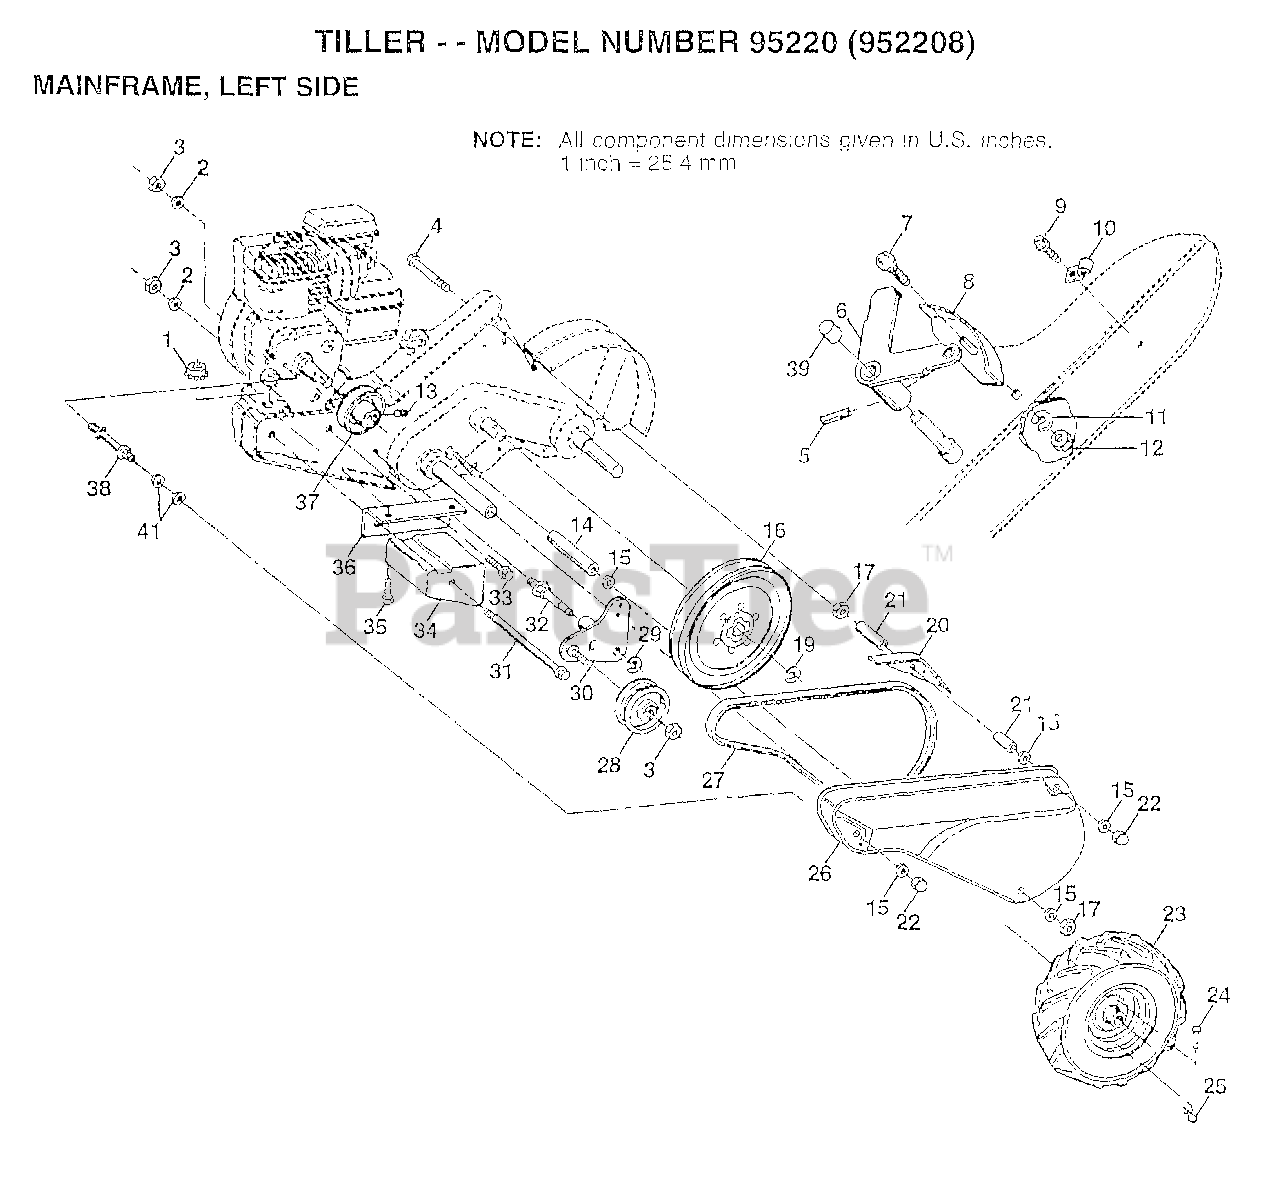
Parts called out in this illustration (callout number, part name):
2	LOCKWASHER
3	NUT.HEX.3/8-16UNC
4	BOLT TI
6	LEVER ASM CRT
7	BOLT
8	PANEL TI
10	CONDIUT CLIP T
11	LOCKWASHER
13	SET SCREW
14	SPACER
15	WASHER
16	SHEAVE.TRANS.
17	NUT.HEX.5/16-18
20	GUARD CRT
21	SPACER.SPLIT
22	NUT TI
23	TIRE.CHV.13X5.0-6
24	RIVET.DRILL.1.75
25	RETAINER M
27	BELT-V
28	PULLEY-IDLER TI
29	KLIP RING
31	BOLT CRT
32	SHIFT ARM CRT
33	BOLT
34	COUNTERWEIGHT CRT
35	BOLT.HEX.5/16-1.5
36	BRACKET LH CRT
37	ENGINE SHEAVE
38	STUD.GUARD.BELT
39	CAP PLUNGER BLACK
41	WASHER
